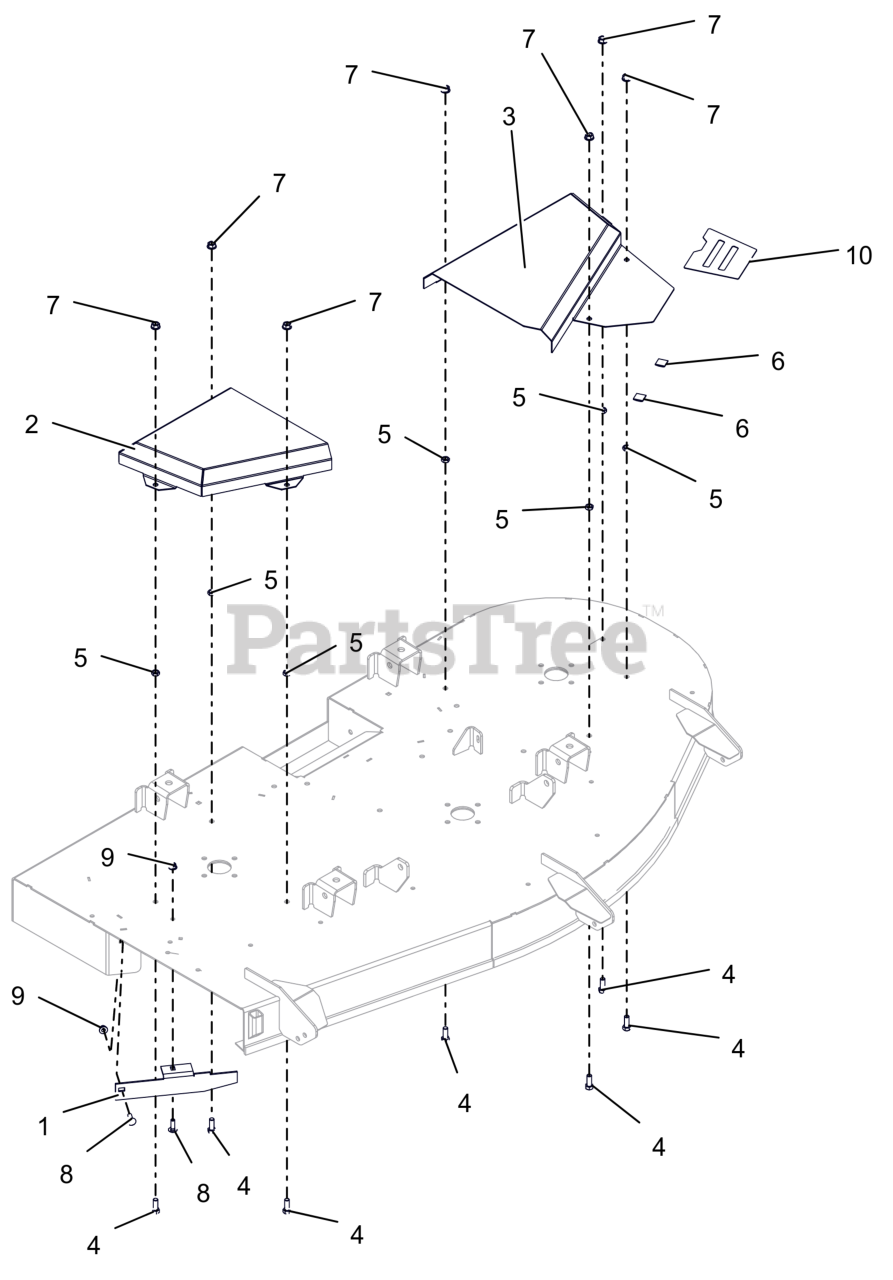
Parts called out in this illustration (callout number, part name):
1	BAFFLE, DISCHARGE 60
2	COVER, RH BELT 60
3	COVER, LH BELT 60
4	BLT,HEX .38-16X1.00 G5 ZCC
5	NUT-JAM .375-16 G2 ZCC
7	NUT-LK-CTR-FLG .375-16 GF ZCC
8	BLT,RHSN .31-18X1.00 G5 ZCC
9	NUT,LK-NYL-FLG .31-18 G5ZC120
10	GRIP TAPE 52-60 BELT COVER
